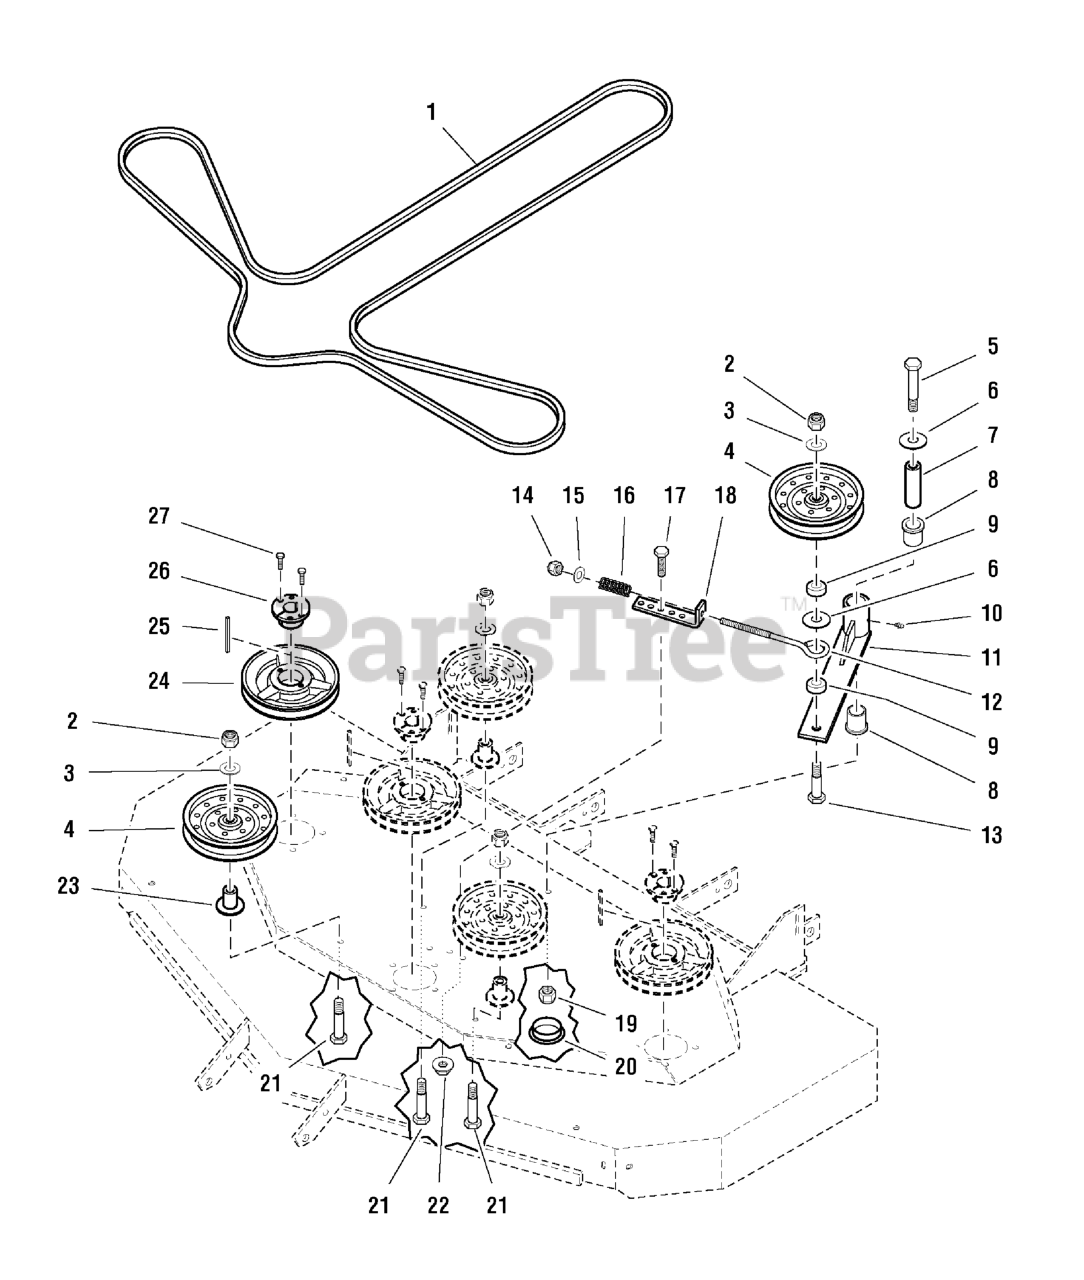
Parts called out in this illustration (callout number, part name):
1	BELT
2	NUT, Hex, Nylon Lock, 1/2-20
3	WASHER, 1/2 SAE
5	BOLT, 1/2-13 X 4-1/2" GD5 YZ
6	WASHER, 1/2" USSZ
7	SPACER, .52 x 1.00 x 3.50
8	BUSHING, FLANGE
9	SPACER, .52 X 1.00 X .44, CZ
10	GREASE FITTING, 1/4-28 Straight
11	WELD, IDLER ARM - RED
12	EYE BOLT, 3/8-16 X 8, 3THRD, 1EYE, CZ
13	BOLT, 1/2-20 X 3" GD5 YZ
14	NUT, 3/8-16 HEX NYLON LOCK
15	WASHER, 3/8 SAE
16	SPRING, COMPRESSION 2" MEDIUM
17	BOLT, 3/8-16 X 1" GD5 CZ
18	SPRING ANCHOR
19	NUT, 1/2-13 HEX NYLON LOCK
20	PLUG, HOLE 2-1/8
21	BOLT, 1/2-20 X 3-1/2" GD5 YZ
22	NUT, 3/8-16 Hex Large Serrated Flange
23	IDLER PULLEY MOUNT - RED
24	PULLEY, SPINDLE, BH66
25	Key, 1/4" Sq. x 2-1/2"
26	BUSHING, Tapered Hub
27	BOLT, 1/4-20 X 1" GD5 CZ
